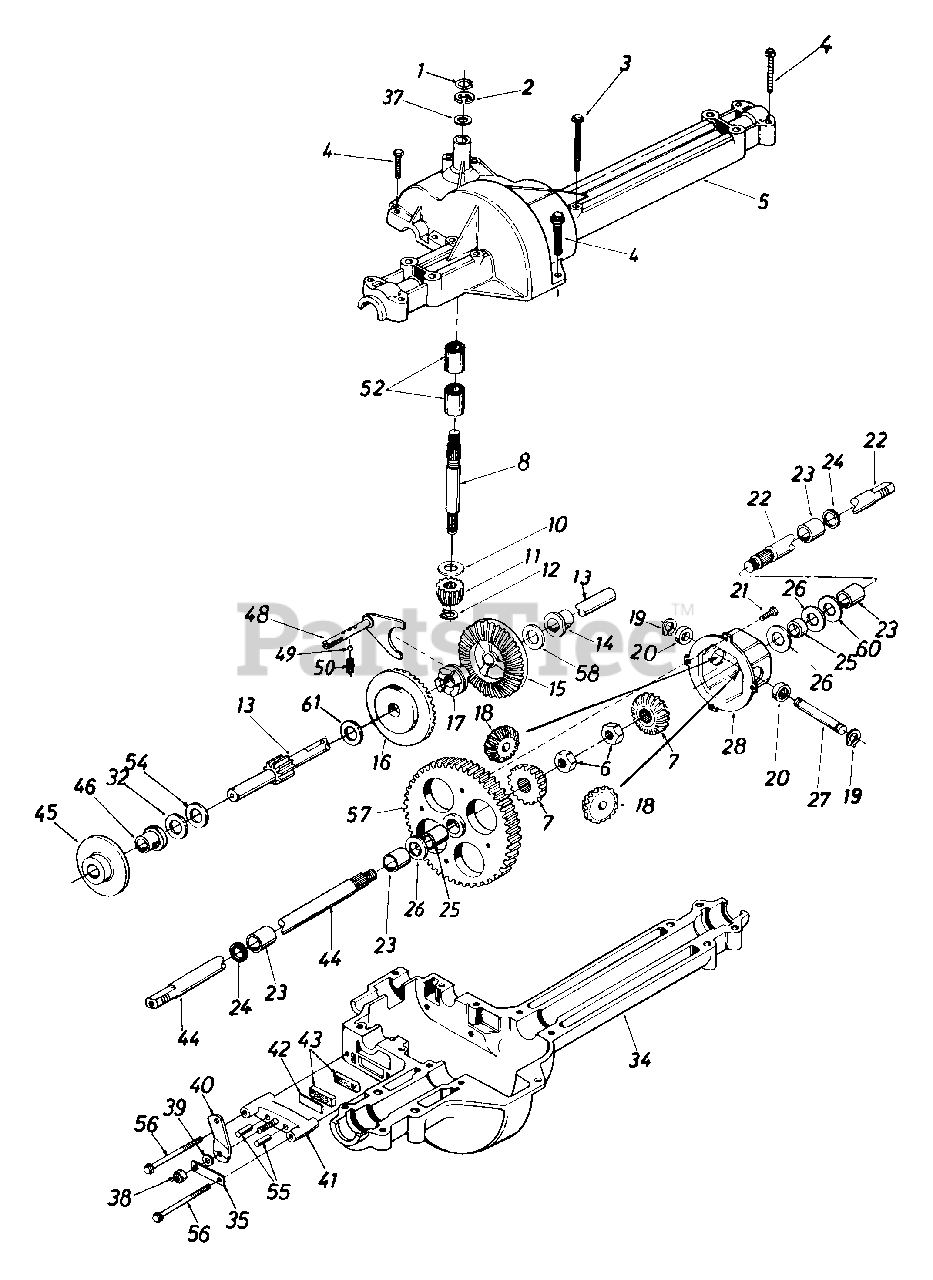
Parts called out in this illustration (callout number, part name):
1	Wire Ring
2	"E"-Ring
3	Hex Bolt 1/4-20 x 1.75" Lg.
4	Hex Tap Scr. 1/4-20 x 1.25" Lg.
5	Upper Housing
6	Hex Jam Nut 1/2-20 Thd.
7	Miter Gear
8	Input Shaft
10	Thrust Washer 5/8" I.D. x 1.25" O.D.
11	Pinion Input 14T
12	Retaining Ring
13	Drive Shaft - L.H. Brake
14	Flange Brg. 5/8" I.D. x 3/4" Lg.
15	Bevel Gear 42T - Small I.D.
16	Bevel Gear 42T - Large I.D.
17	Clutch Collar
18	Miter Gear 15T (H.D.)
19	Snap Ring
20	Thrust Bearing
21	Pan Head Scr. 1/4-20 x .50" Lg. w/Patch
22	Axle R.H.
23	Sleeve Bearing 3/4" I.D. x 1.0" Lg.
24	Oil Seal 3/4" I.D.
25	Axle Spacer
26	Fl-Wash. .760" I.D. x 1.5" O.D.
27	Cross Shaft
28	Differential Can Ass'y.
32	Washer
32	Thrust Wash. 5/8" I.D. x 1" O.D. x .025" Thk.
32	Fl-Wash. 5/8" I.D. x 1" O.D. x .030" Thk.
32	Thrust Wash. 5/8" I.D. x 1" O.D. x .035" Thk.
34	Lower Housing
35	Anti-Rotation Brkt.
37	Washer
37	Fl-Wash. 5/8" I.D. x 1" O.D. x .020" Thk.
37	Fl-Wash. 5/8" I.D. x 1" O.D. x .030" Thk.
37	Fl-Wash. 5/8" I.D. x 1" O.D. x .040" Thk.
38	Hex Nut 5/16-24 Thd.
39	Fl-Wash. .344" I.D. x .875" O.D.
40	Actuating Arm
41	Brake Yoke
42	Puck Plate
43	Brake Puck
44	Axle L.H.
45	Brake Disc
46	Flange Bearing 5/8" I.D. x 15/16" Lg.
48	Shift Fork Ass'y.
49	Ball Detent .250" Dia.
50	Spring Detent
52	Needle Brg. 5/8" I.D. x 1/2" Lg.
54	Fl-Wash. 5/8" I.D. x 1" O.D. x .020 Thk.
55	Actuating Pin 5/16" Dia.
56	Hex Wash Hd. Self-Tap Scr. 1/4-20 Thd.
57	Differential Gear 58T
58	Fl-Wash. 5/8" I.D. x 1" O.D. x .020 Thk.
60	Washer
60	Fl-Wash. .76" I.D. x 1.5" O.D. x .010" Thk.
60	Fl-Wash. .76" I.D. x 1.5" O.D. x .020" Thk.
60	Fl-Wash. .76" I.D. x 1.5" O.D. x .030" Thk.
60	Fl-Wash. .76" I.D. x 1.5" O.D. x .060" Thk.
61	Thrust Washer
